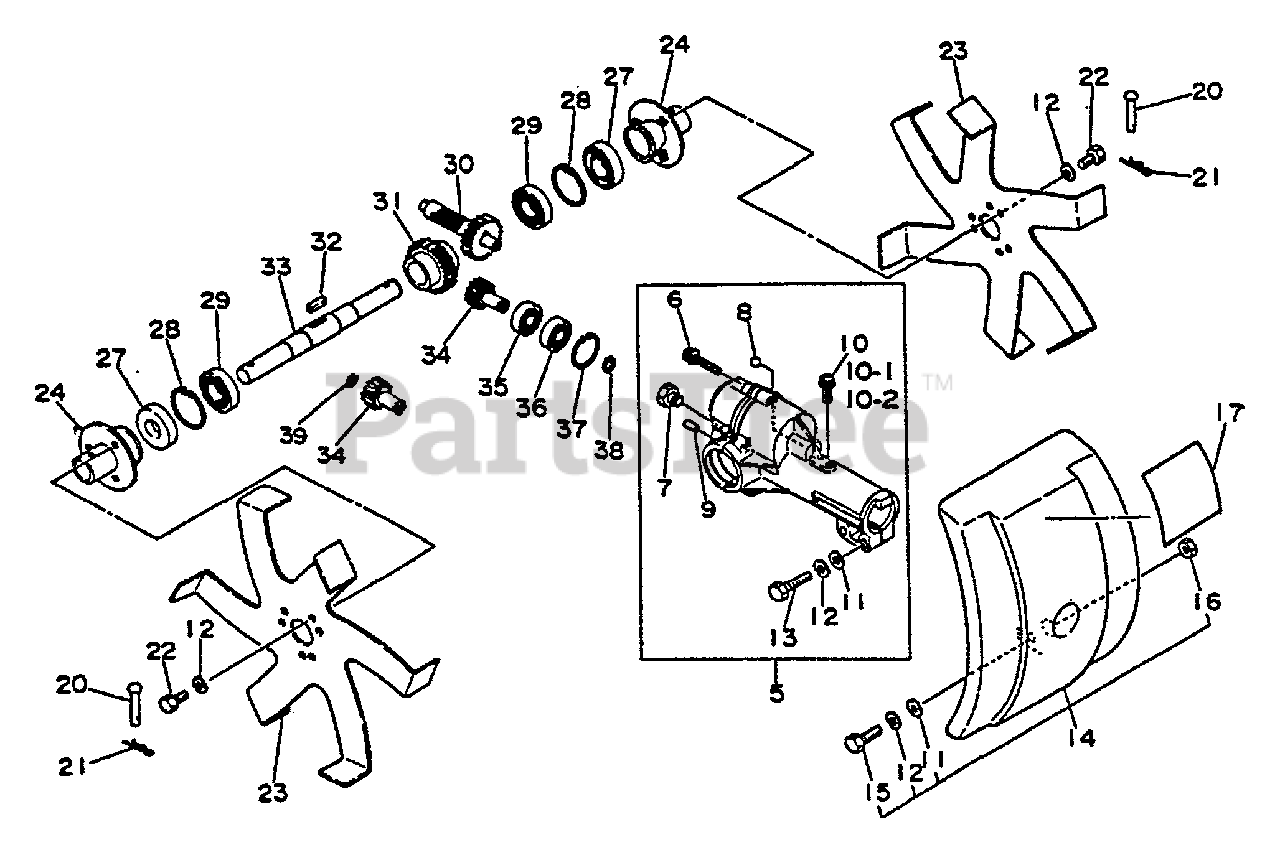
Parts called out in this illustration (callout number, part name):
5	CASE, GEAR
6	SCREW 4×25
7	BOLT 8×8 SP
8	BALL, STEEL
9	PIN, DOWEL
10	SCREW 5×14
10-1	WASHER, SPRING 5
10-2	WASHER, FLAT 5.5×10×0.8
11	WASHER 6.5×11.5×0.8
12	WASHER, SPRING 6
13	BOLT 6×25
14	SHIELD
15	BOLT 6×20
16	NUT, HEX M6
17	LABEL
20	PIN, CLEVIS
21	PIN, COTTER 5
22	BOLT 6×10
24	HUB, TINE
27	SEAL, OIL 17
28	E-RING 30
29	BEARING, BALL 6903
31	WHEEL, WORM
33	SHAFT, WORM WHEEL
34	GEAR
35	BEARING, BALL 6001
36	BEARING, BALL 6001Z
37	RING, SNAP 28
38	RING, RETAINING - 12
39	RING, RETAINING - 7
